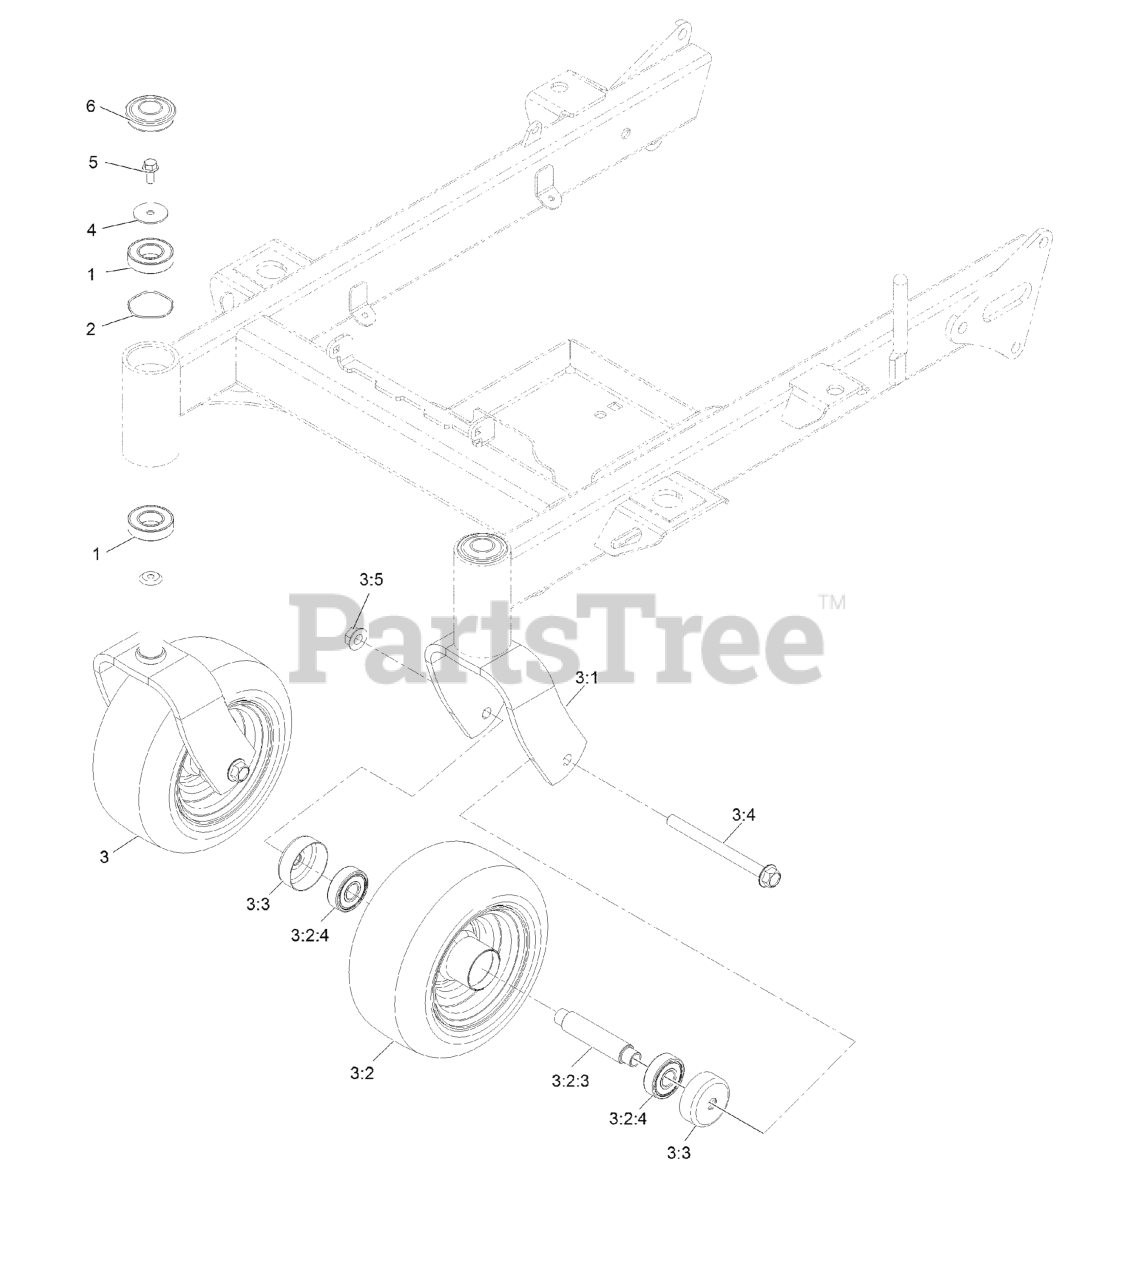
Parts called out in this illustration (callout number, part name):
1	BEARING-BALL
3	ASM-Caster Fork W/Tire
3:1	ASM-CASTER FORK
3:2	ASM-TIRE&WHL SP 9X4.50-5
3:2:3	AXLE-CASTER
3:2:4	BEARING
3:3	GUARD, SEAL
3:4	SCREW-HHF
4	WASHER-FLAT
5	SCREW-HHF
6	CAP-GREASE
